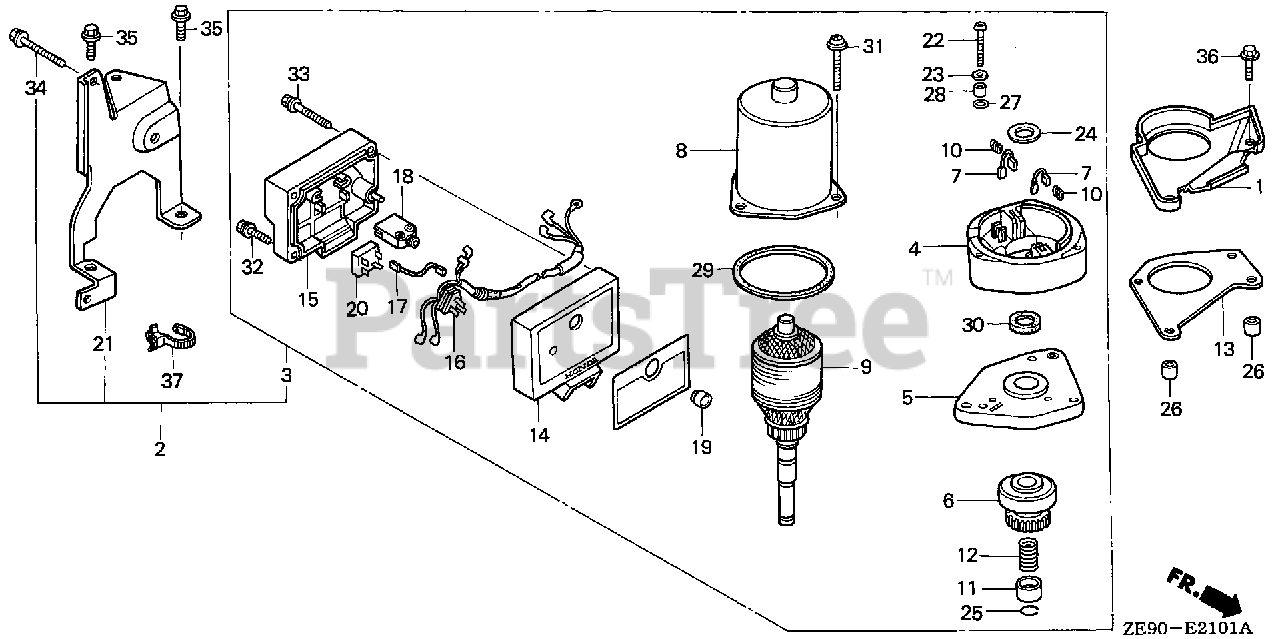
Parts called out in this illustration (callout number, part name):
1	PLATE, SIDE
2	STARTER MOTOR ASSY. (NOT AVAILABLE)
3	STARTER MOTOR ASSY. (NOT AVAILABLE)
4	HOUSING, CENTER
5	HOUSING, PINION
9	ARMATURE (NOT AVAILABLE)
10	SPRING, BRUSH RETURN
11	STOPPER, PINION
12	SPRING, COIL
13	BRACKET, STARTER MOTOR
18	SWITCH, STARTER (A.C. 380V/16A)
18	SWITCH, STARTER (A.C. 250V/16A)
21	BRACKET, SWITCH BOX
22	SCREW, TRUSS (4X30)
23	WASHER, STAR (4MM)
25	RING, RETAINING
26	PIN A, DOWEL (10X14)
31	SCREW-WASHER (5X40)
32	SCREW-WASHER (4X20)
33	SCREW-WASHER (4X30)
34	BOLT, FLANGE (6X40)
35	BOLT, FLANGE (8X25)
36	BOLT, FLANGE (8X28)
37	STRAP, CABLE (105MM) (BLACK)
